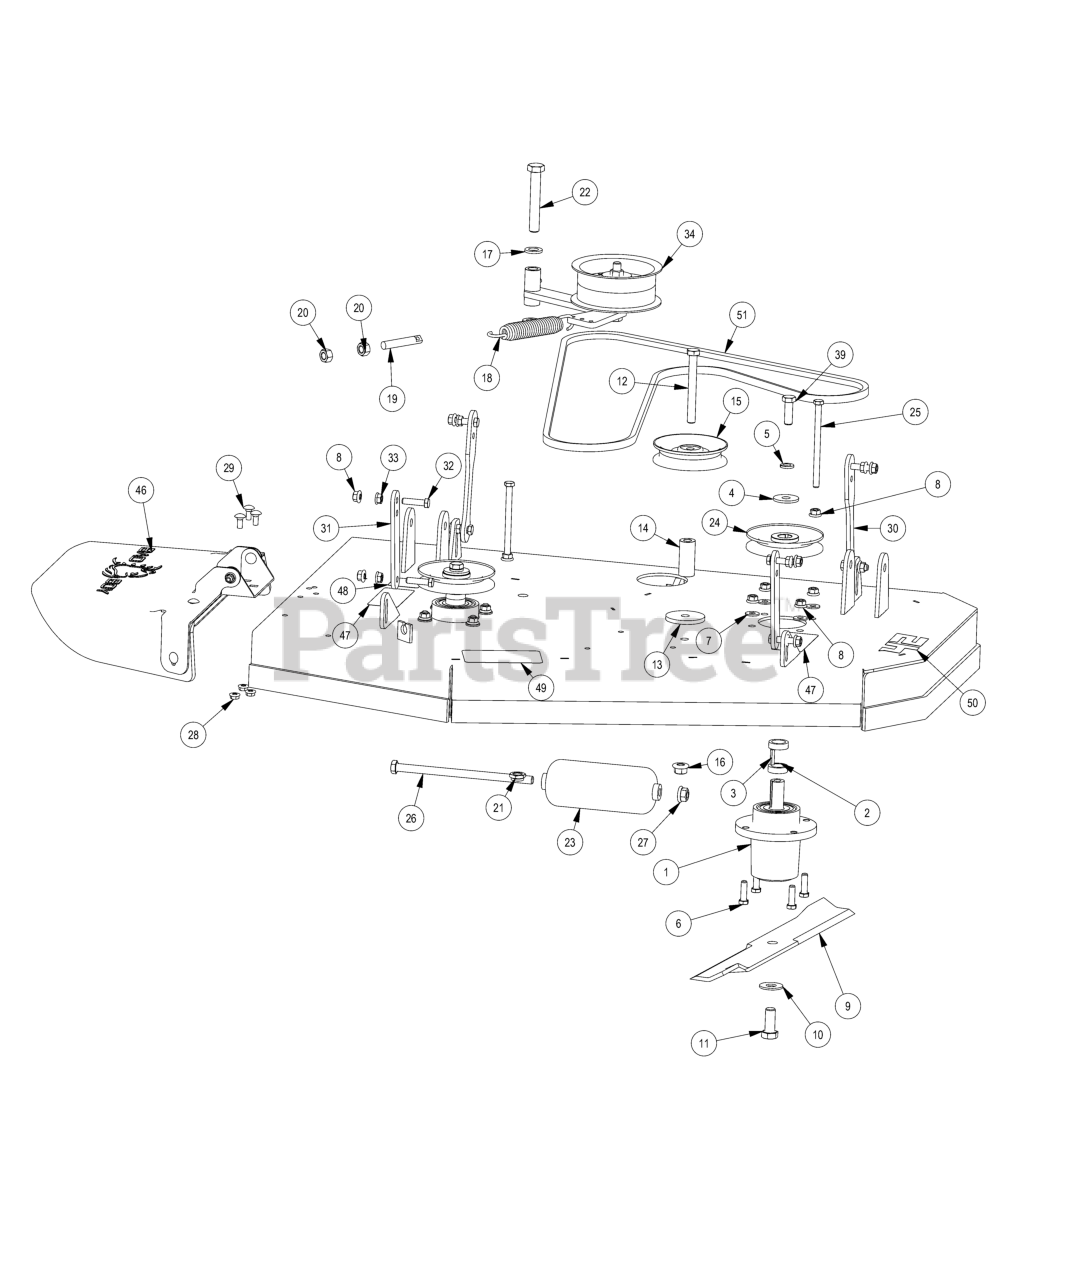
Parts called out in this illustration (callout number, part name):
1	36'' Revolt Spindle Assembly
2	36 Deck Spindle Spacer
3	3/16 X 1 SQ MACHINERY KEY 1018 STL ZINC
4	1/2 BELLEVILLE WASHER (1-5/8 OD X .140 THK) ZINC
5	1/2 SPLIT LOCKWASHER (GR.8) ZINC/YELLOW
6	3/8-16 X 1-1/4 HEX CAP SCREW (GR.5) ZINC
7	5/16 USS FLAT WASHER (7/8 OD) ZINC
8	3/8-16 NYLON INSERT FLANGE LOCKNUT (GR.F) ZINC
9	60" High Lift Fusion Blade
10	5/8'' Flat Washer
11	5/8-18 X 1-1/2 HEX CAP SCREW (GR.8) ZINC YELLOW
12	1/2-13 X 4-1/2 HEX CAP SCREW (GR.5) ZINC
13	MZ Deck Idler Spacer
14	2019 Revolt Stationary Idle Spacer
15	5 V Idler Pulley 1/2" Bore
16	1/2-13 NYLON INSERT FLANGE LOCKNUT ZINC
17	.635 ID X 1.120 OD X .140 THICK FLAT WASHER NYLON
18	Deck Idler Spring
19	All Thread
20	1/2-13 HEX NUT ZINC
21	5/8-11 NYLON INSERT JAM LOCKNUT ZINC
22	5/8-11 X 4 HEX CAP SCREW (GR.8) ZINC YELLOW
23	3in deck roller
24	60" MZ Deck Pulley (Representation Only)
25	3/8-16 X 5-1/2 HEX CAP SCREW (GR.5) ZINC
26	1/2-13 X 9 HEX CAP SCREW (GR.5) ZINC
27	1/2-13 HEX FLANGE AUTO OVAL LOCKNUT (GR.F) ZINC/WAX
28	5/16-18 HEX SERRATED FLANGE NUT HARD/ZINC
29	5/16-18 x 3/4 Carriage Bolt
30	2019 Stand-On Rear Deck Hanger
31	2019 Revolt Front Deck Hanger
32	3/8-16 X 1-1/2 HEX CAP SCREW (GR.5) ZINC
33	3/8-16 HEX SERRATED FLANGE NUT HARD/ZINC
34	5 3/4" Deck Idler Pulley
35	2020 36 Deck Idler Arm Weldment
36	1/4-28 Grease Fitting
37	1/2-13 X 3-1/2 HEX CAP SCREW (GR.5) ZINC
39	1/2-20 X 1-1/2 HEX CAP SCREW (GR.5) ZINC
40	2024 42 SD Stand On Deck weldment
46	MZ Discharge Chute Assembly
47	Danger Decal-Spindle/Discharge
48	Deck Impact Patent Decal 9591803
49	36" Revolt Deck Belt Route Decal
50	42" Deck Decal
51	2020 Walk-Behind 36 Deck Belt
